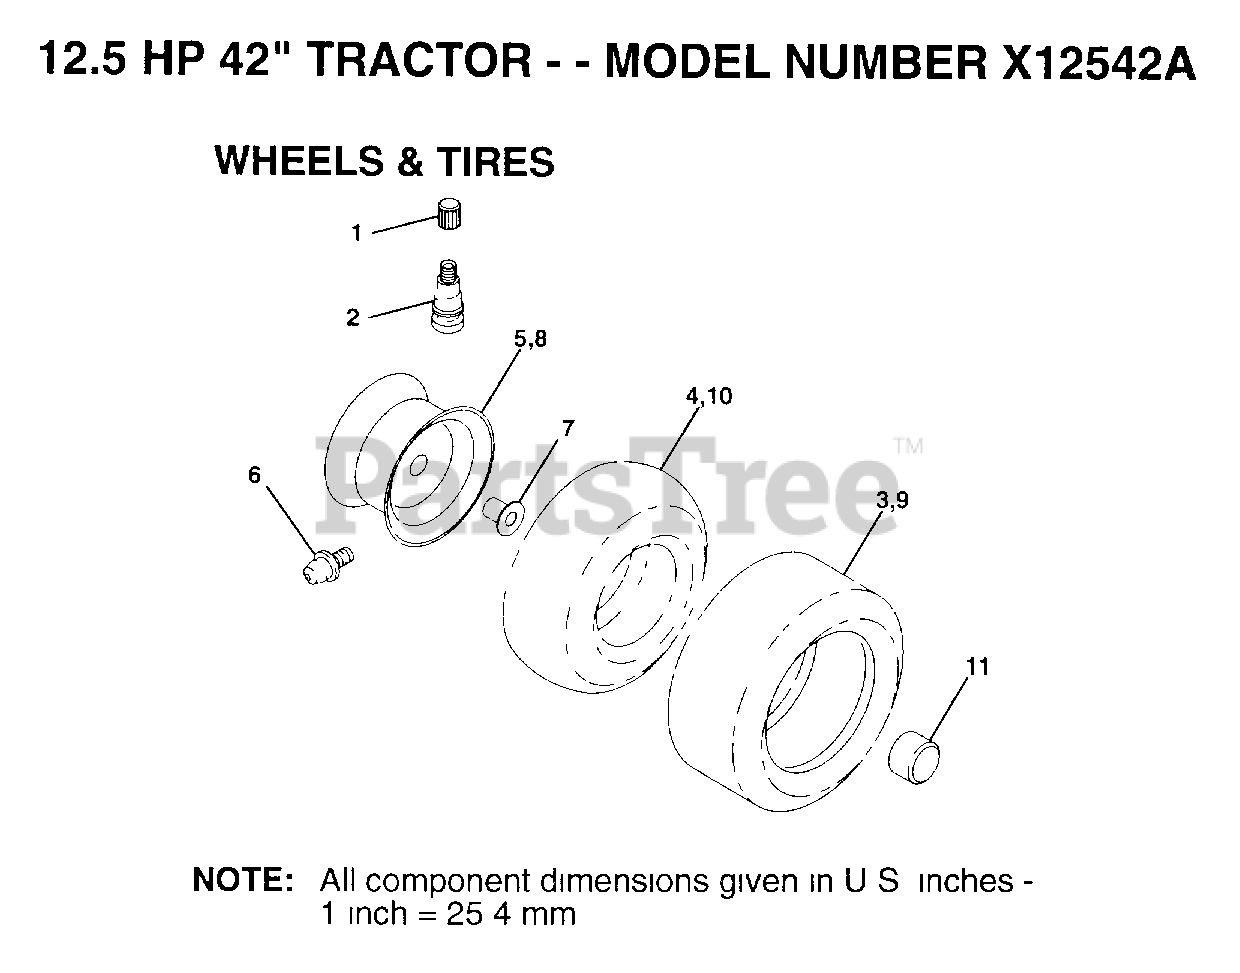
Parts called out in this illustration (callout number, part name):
1	VALVE CAP
2	VALVE STEM LT
4	TUBE.5.3/4.5/6
6	FITTING LT
7	"FLANGE, BEARING"
9	TIRE.20X8-8
10	TUBE.18X9.5-8
11	HUB CAP
